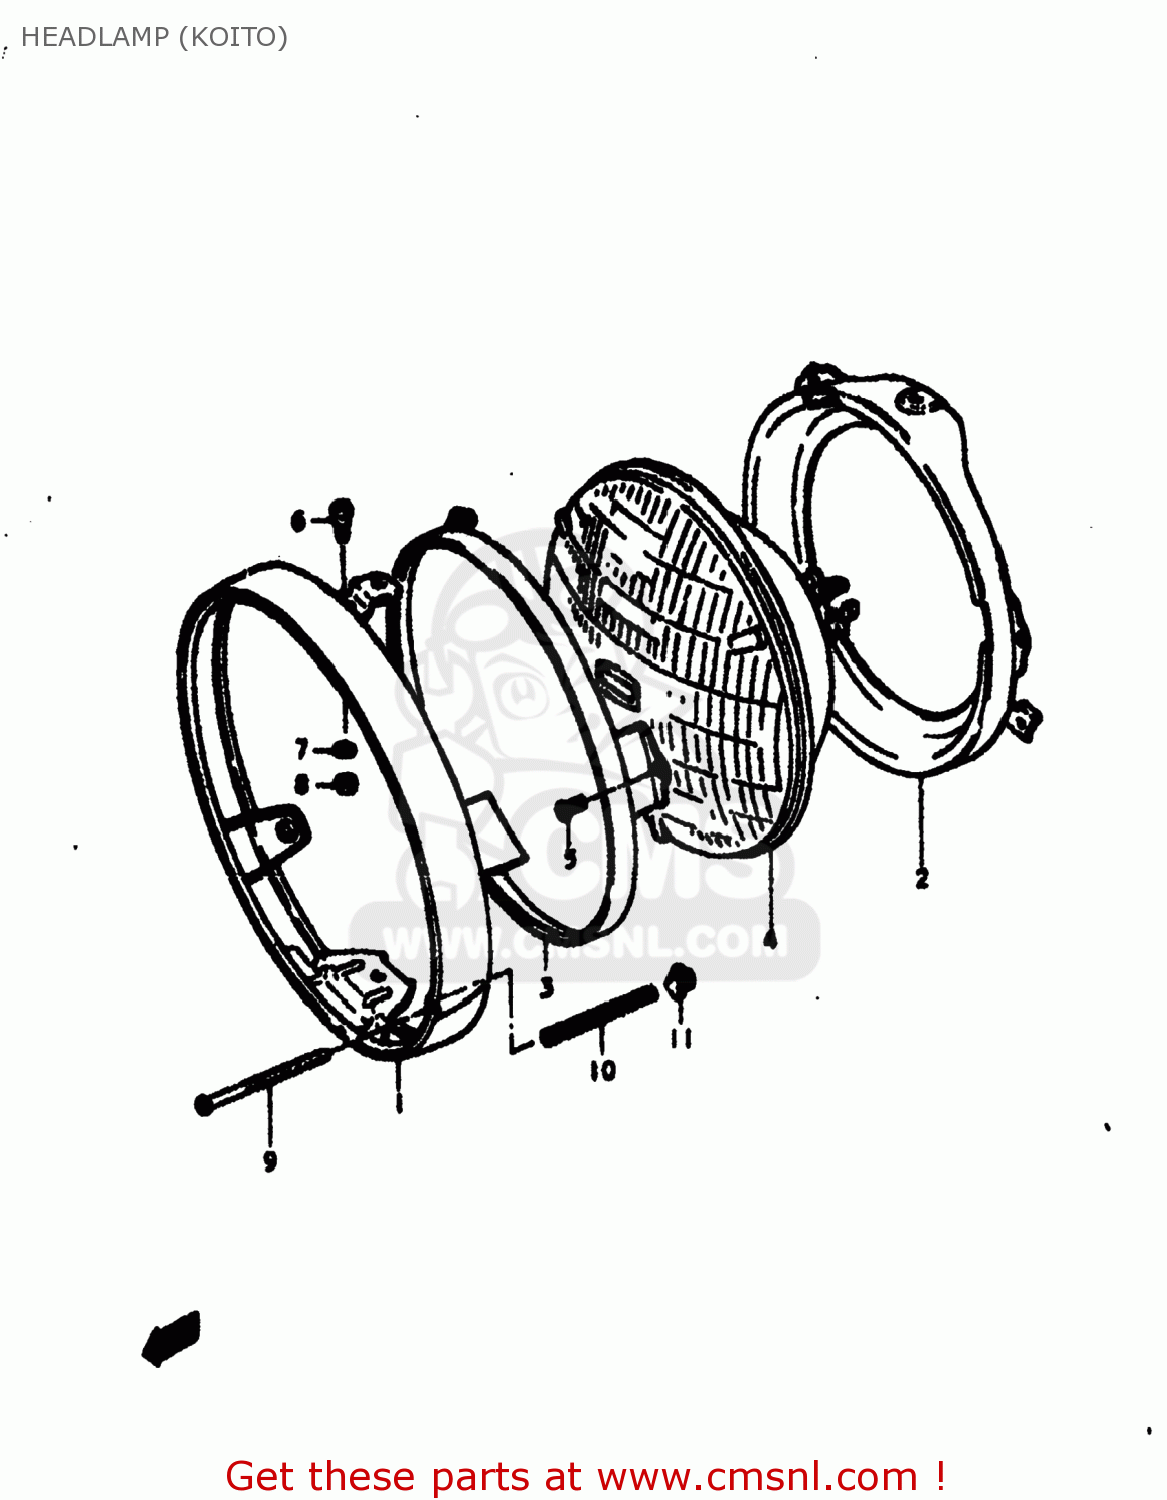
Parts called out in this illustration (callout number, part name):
1	RIM
2	RING
3	RETAINING RING
4	UNIT,HEADLAMP
5	SCREW
6	H/LAMP LENS UNIT FITING SCRE
7	LOCK WASHER
8	NUT
9	SCREW,HEADLAMP ADJUST
10	SPRING,ADJUSTING
11	NUT
